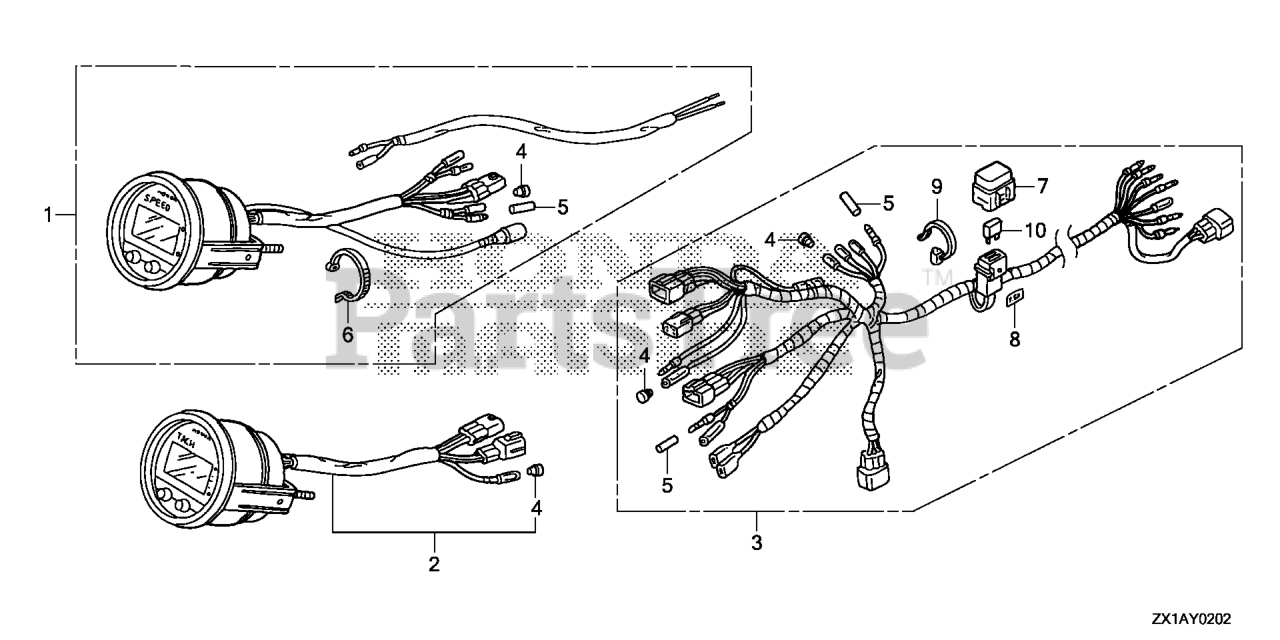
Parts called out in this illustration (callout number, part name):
1	SPEEDOMETER KIT (DIGITAL)(USA) (NOT AVAILABLE)
1	SPEEDOMETER KIT (DIGITAL) (NOT AVAILABLE)
2	METER KIT, TACHO (DIGITAL)(USA) (NOT AVAILABLE)
2	METER KIT, TACHO (DIGITAL) (USE FOR 32540-ZY3-800/801)
3	HARNESS ASSY., METER (A)(DIGITAL)
4	PLUG, CONNECTOR (INNER) (TROLLING CONTROL)
5	PLUG, CONNECTOR (OUTER) (ENGINE NO.)
6	BAND (BLACK 3.5X140)
7	COVER ASSY., FUSE (7.5A)
8	MARK, FUSE (7.5A)
9	TIE, CABLE
10	FUSE, BLADE (7.5A)
